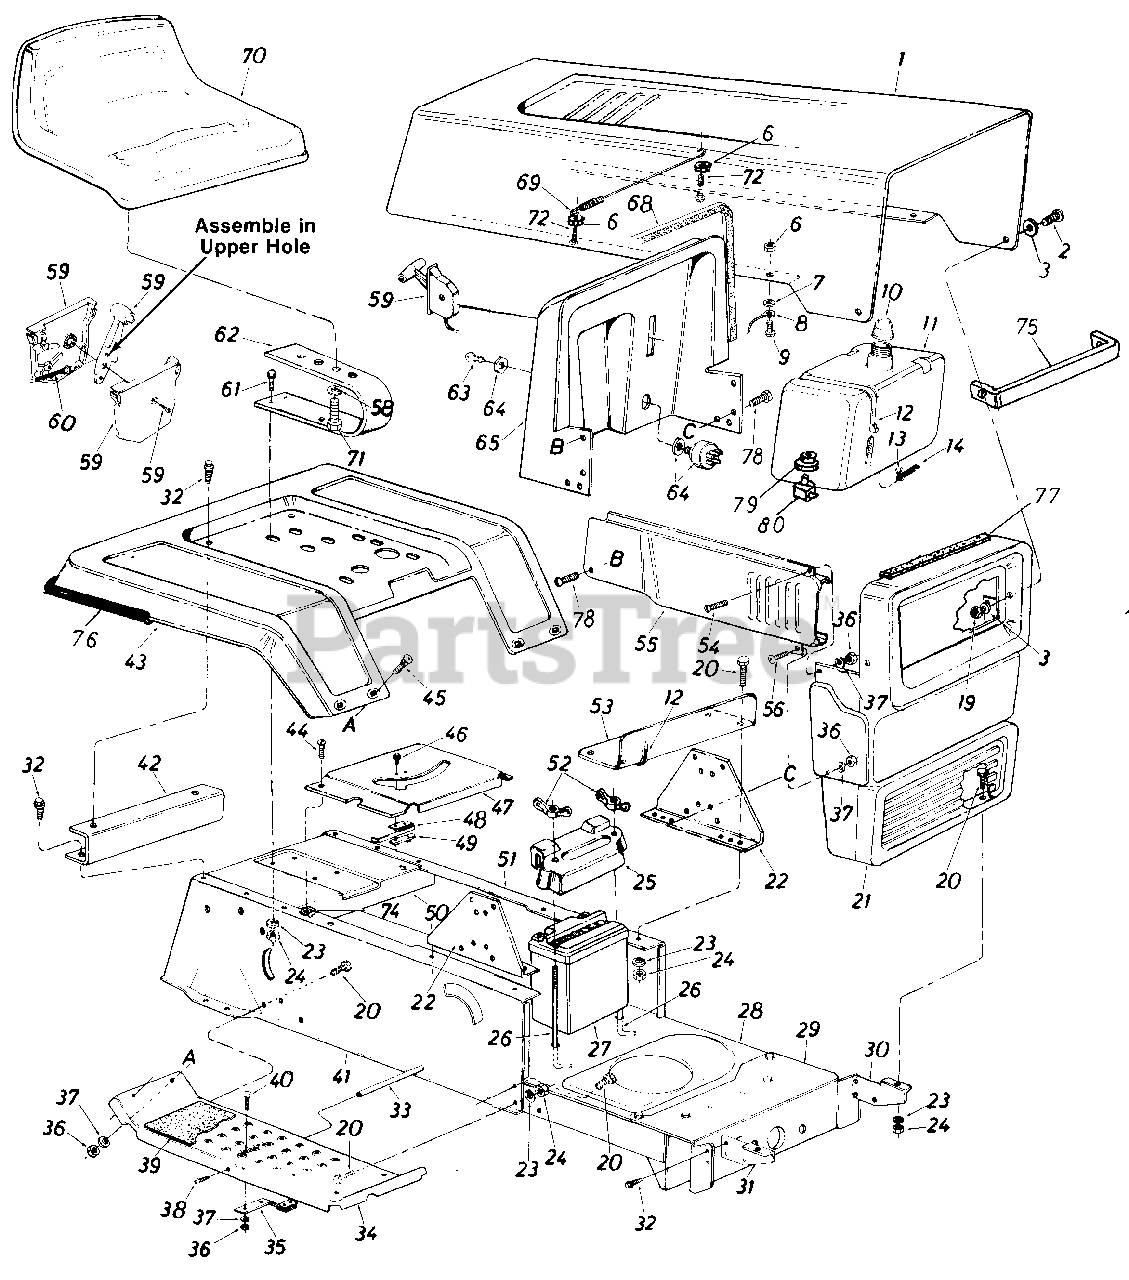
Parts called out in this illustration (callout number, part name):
1	Hood
2	Hex Bolt 1/4-20 x .62" Lg.*
3	Fl-Wash 296" I.D. x .62" O.D.
6	Hex Sems Nut #10-24 Thd.
7	Fl-Wash. .203" I.D. x .41" O.D. x .040
8	Hood Stop
9	Truss Hd. Scr. #10-24 x 1/2"
10	Fuel Cap Gauge
11	Fuel Tank
12	Tie Strap
13	Hose Clamp
14	Fuel Line
19	Hex L-Nut 1/4-20 Thd.
20	Hex Bolt 5/16-18 x .75" Lg.
21	Grille
22	Dash Support Bracket
23	L-Wash. 5/16" I.D.
24	Hex Nut 5/16-18 Thd.
25	Battery Cover
26	Battery Hold Down Rod
27	12V Battery
28	Lower Frame
29	Front Pivot Brk't.
30	Grille Mount Brk't. L.H.
33	Running Board Rod
34	Running Board
35	Blade Brake Ass'y.
36	Hex Nut 1/4-20 Thd.
37	L-Wash. 1/4" I.D.
38	Truss Mach. Scr. 5/16-18 x .75" Lg.
39	Foot Pad
40	Carriage Bolt 1/4-20 x .62" Lg.*
41	R.H. Side Frame
42	Fender Mount Brace
43	Rear Fender
44	Truss Mach. Tap Screw #10 x .50"
45	Carriage Bolt 1/4-20 x .50" Lg.*
46	Truss Hd. Scr. #10-24 x .50" Lg.
47	Transmission Panel
48	Reverse Safety Switch
49	Insulator Nut Plate
50	Hitch Plate
51	L.H. Side Frame
52	Wing Nut 1/4-20 Plastic
53	Fuel Tank Support
54	Truss Hd. Scr. 1/4-20 x .75" Lg.*
55	Side Cover R.H.
56	Truss Mach. Scr. 1/4-20 x .50" Lg.
58	L-Wash. 1/2" I.D.
59	Throttle Control Box Ass'y.
60	Throttle Control Wire
61	Hex Bolt 5/16-18 x 1.00" Lg.
62	Seat Spring 5.5" High
63	Ignition Key
64	Ignition Switch
65	Dash Panel
68	Trim Strip 27" Lg.
69	Hood Spring
70	Seat Ass'y.
71	Hex Bolt 1/2-13 x 1.0" Lg.
72	Hex Bolt #10-24 x 1.0" Lg.
74	Speed Nut #10Z
75	Tie Strap-Grille/Side Panel
76	Trim Strip 81" Lg.
77	Foam Strip 3/8 x 1 x 14" Lg.
78	Hex Wash. Hd. Tap Scr. x .75" Lg.
79	Bushing
80	90 Elbow
